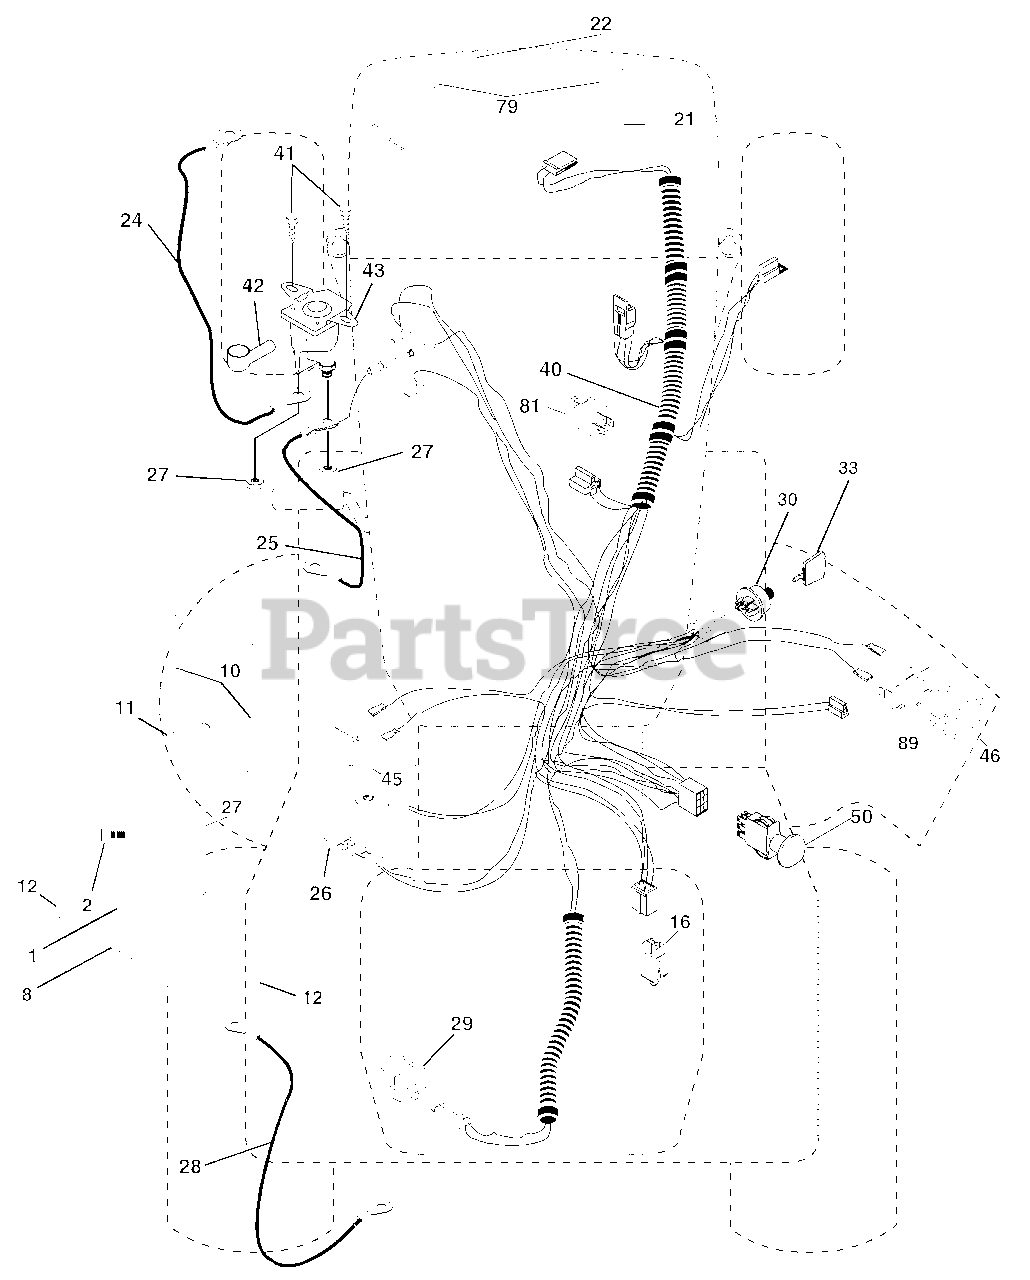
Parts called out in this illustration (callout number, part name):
1	Battery
2	Bolt Hex Head 1/4-20 x 3/4
8	Tray, Battery
10	Bolt Btr Frt 1/4-20 X 7.5 zinc
11	Holdown Battery Front Mount
12	Nut Push Nylon 1/4"
16	Switch Interlock Push-In
21	Harness Headlight w/Bulbs
22	Bulb Light
24	Cable, Battery
25	Cable, Battery
26	Fuse
27	Nut Keps Hex 1/4-20 Unc
28	Cable, Ground
29	Switch, Plunger
30	Switch, Ign
33	Key
40	Harness, Ignition
41	Screw 1/4-20 x 1/2
42	Cover, Terminal Red
43	Solenoid
45	Ammeter
46	Hourmeter Snap-In
50	Switch, PTO
79	Socket, Light Bulb
81	Relay Asm.
89	Bracket Snap-In
